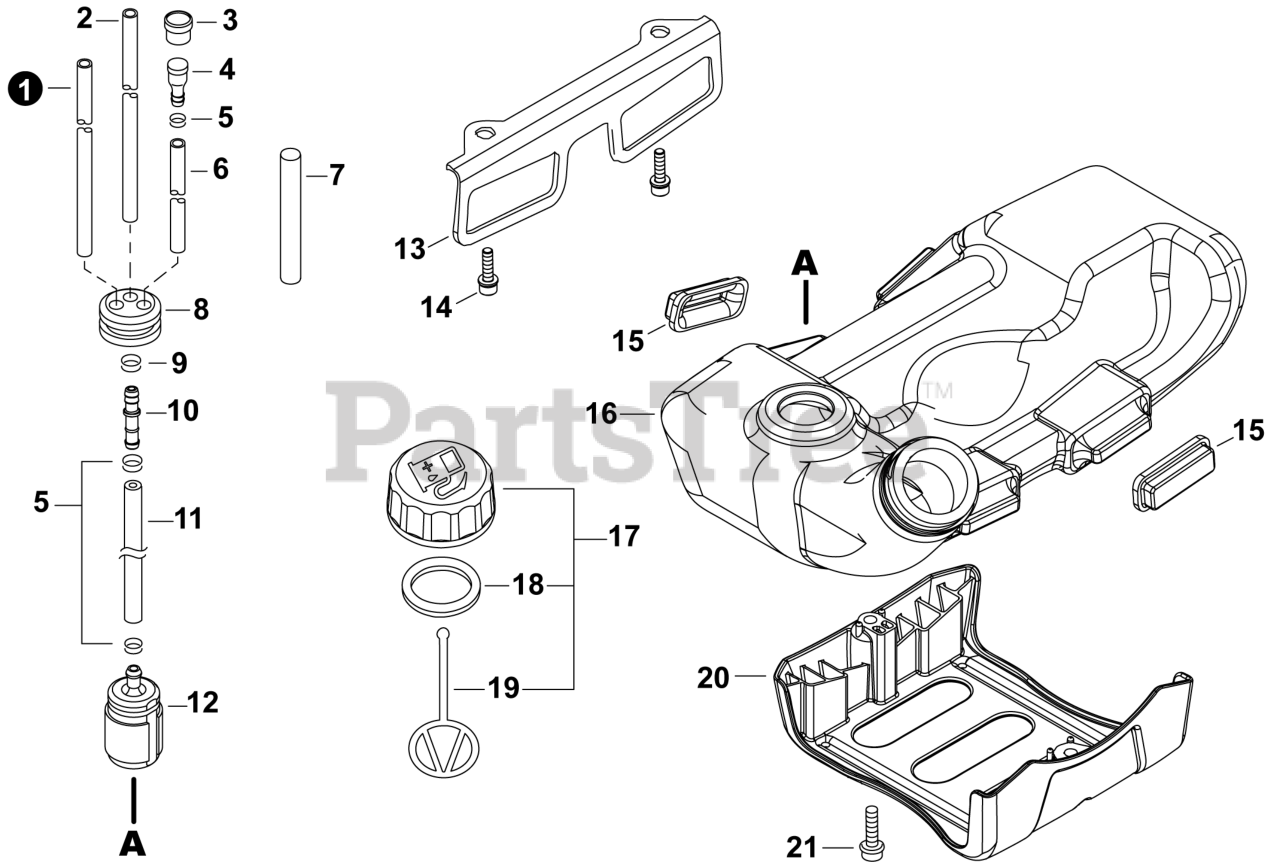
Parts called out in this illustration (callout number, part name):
1	PIPE, FUEL
2	PIPE, FUEL 3×5×180
3	HOLDER, VENT
4	VENT ASSY
5	CLIP Ø6
6	PIPE, FUEL 3×6×140 BLACK
7	TUBE, INSULATOR 8×9×111
8	GROMMET, FUEL
9	CLIP 5.5
10	CONNECTOR, PIPE
11	PIPE, FUEL 3×6×130 BLACK
12	FILTER, FUEL
13	BRACKET, FUEL TANK
14	BOLT, TORX 5×16
15	CUSHION, FUEL TANK
16	TANK, FUEL
17	CAP ASSY, FUEL
18	GASKET, FUEL CAP
19	CONNECTOR, CAP L= 123
20	GUARD, FUEL TANK
21	BOLT, TORX 5×16
